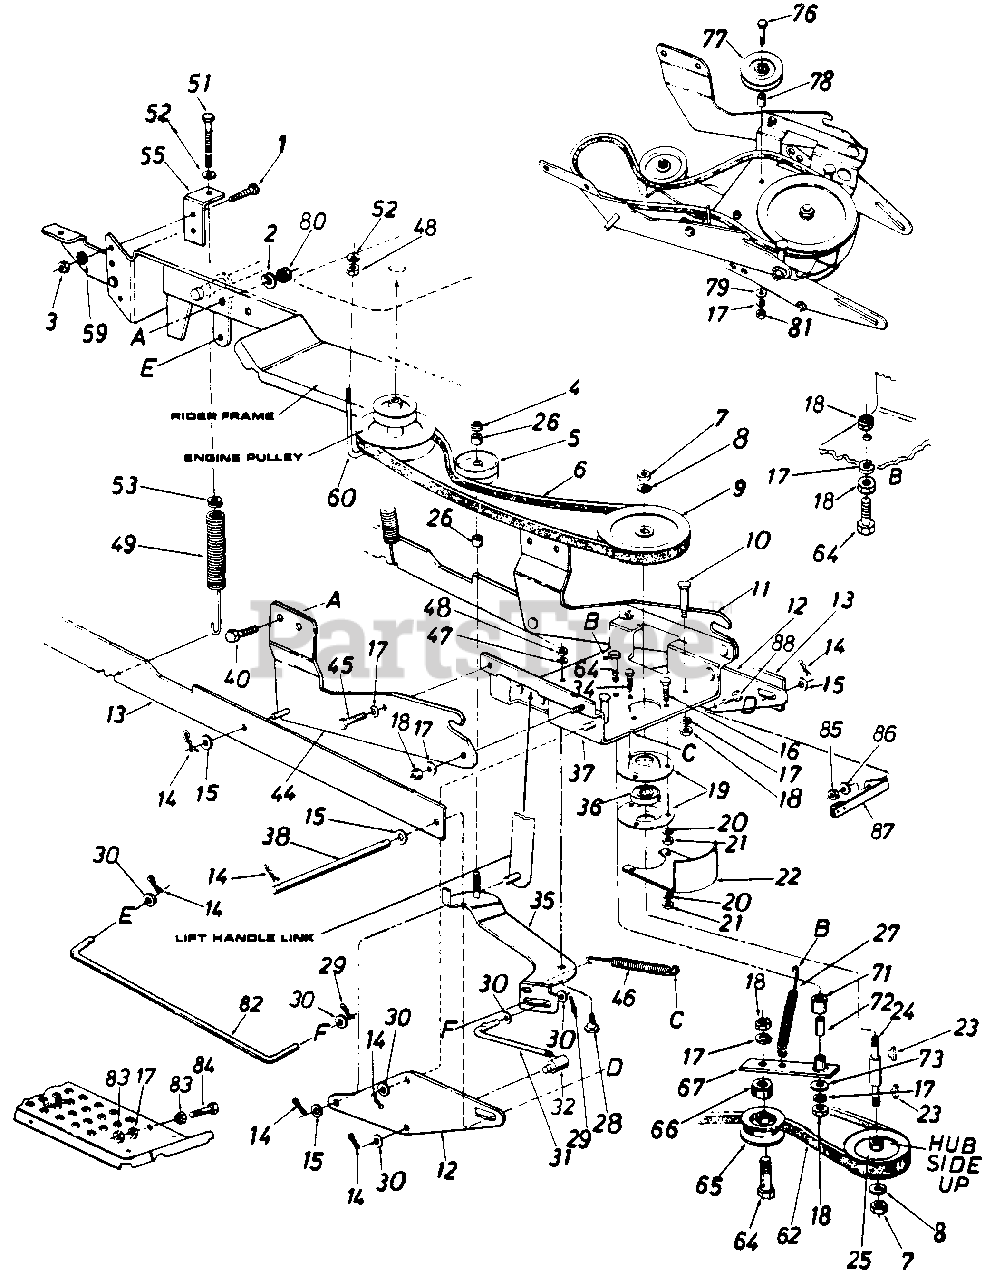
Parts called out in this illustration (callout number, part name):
1	Hex Bolt 1/4-28 x 1.0" Lg.-Gr. 5
2	L-Wash. 1/4" I.D.
3	Hex Nut 1/4-28 Thd.
4	Hex Cent. L-Nut 3/8-16 Thd.
5	Idler Pulley
6	"V"-Belt
7	Hex Jam Nut 5/8-11 Thd.
8	L-Wash. 5/8" I.D.
9	5/8 Pulley x 6.5" O.D.
10	Shoulder Bolt
11	Channel Support Brkt.-Pl.H.
12	Linkage Brkt.
13	Linkage Arm Ass'y.
14	Intern. Cotter Pin .50" Dia.
16	Hex Bolt 5/16-18 x 1.25" Lg.
17	L-Wash. 3/8" I.D.
18	Hex Jam Nut 3/8-16 Thd.
19	Bearing Housing
20	L-Wash. 5/16" I.D.
21	Hex Nut 5/118 Thd.
24	Pulley Spindle
25	5/8 Pulley 6.28n l.D. x 5.56" O.D.
26	Spacer .383" I.D. x .503" O.D. x.562" Lg.
27	Extension Spring .54" O.D. x 5.25"
28	Shoulder Bolt
29	Cotter Pin 3/32n Dia.
31	Control Rod
32	Ferrule
34	Hex Sems Bolt 5/16-18 x .75" Lg.
35	Clutch Idler Brkt. Ass'y.
36	Ball Bearing
37	Channel Ass'y.
38	Lift Handle Shaft
40	Hex Selt-Tap Scr. 1/420 x .75" Lg.
44	Channel Supporting Brkt.-L.H.
45	Hex Bolt 3/8-16 x 1" Lg.
46	Extension Spring
47	L-Wash. 6/16" l.D.
48	Hex Nut 5/16-18 Thd.
49	Helper Spring
51	Hex Bolt 5/16-18 x 2.0" Lg. Special
52	Bell-Wash. .345" I.D. x .88" O.D. x .06"
53	Spring Insert
60	J-Bolt 5/16-18 Thd.
62	"V"-Belt
64	Hex Bolt 3/8-16 x 2" Lg.
65	Idler Pulley
66	Spacer .385" l.D. x .503" O.D. x .562" Lg.
67	Idler Arm Ass'y.
71	Spacer.38" l.D.
72	Spacer .3775" I.D. x .6" O.D. x 8.3" Lg.
73	Fl-Wash. 3/8" l.D. x 1" O.D. x 1.27"
76	Hex Bolt 3/8-16 x 2.5" Lg. (Grade 5)
77	Idler Pulley .38" l.D. x 3.06' O.D.
78	Spacer .385" l.D. x .63" O.D. x.76" Lg.
79	Fl-Wash. .39" l.D. x 1-3/4" O.D. x 3/16"
80	Hex L-Nut 1/4-20 Thd.
81	Hex Nut 3/8-16 Thd.
82	Clutch Control Rod
83	Hex Nut 3/8-24 Thd.
84	Hex Bolt 3/8-24 x 2.25" Lg.
85	Hex Nut 3/8-16 Thd.
86	Bell-Wash. 3/8" I.D.
87	Auger Brake Brkt. Ass'y.
88	Hex Bolt 3/8-16 x 5/8" Lg.
